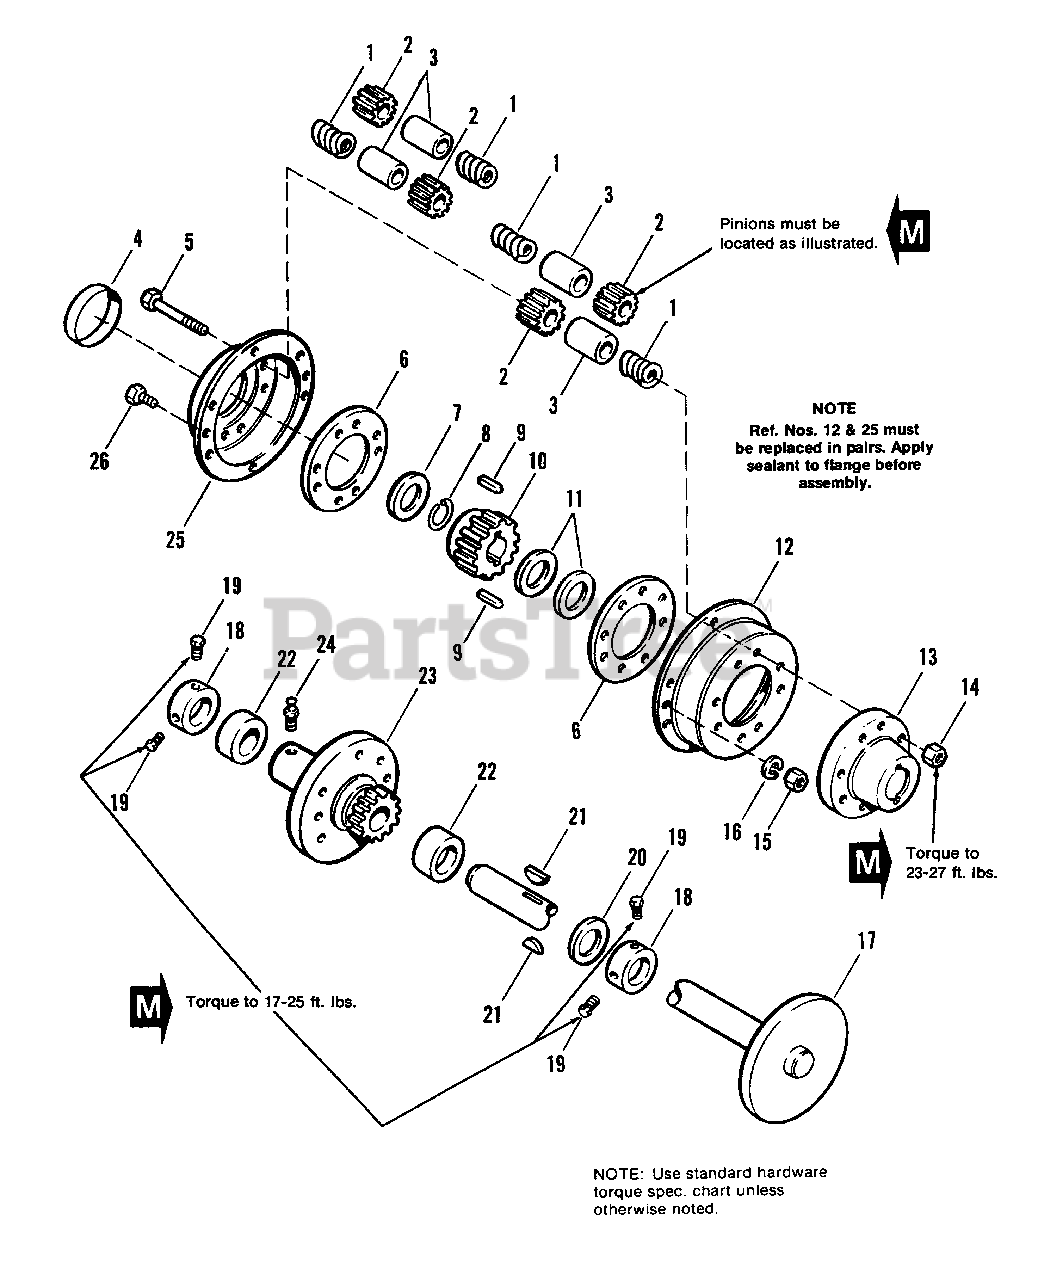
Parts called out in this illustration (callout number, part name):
2	* PINION, Differential
3	* SPINDLE, Differential
4	* SEAL, Cover
5	* CAPSCREW, Hex Hd., 3/8-16 x 2-1/2
6	* RING, Spacer
8	RING, Retaining
9	KEY, Hi-Pro
10	GEAR, Differential
12	* COVER, Differential
13	* CARRIER, Differential
14	* LOCKNUT, Hex, 3/8-16
15	* NUT, Hex, Full, 1/4-20
16	* LOCKWASHER, 1/4
17	AXLE ASSY., Rear
18	COLLAR, Set
19	SETSCREW, 5/16-18 x 1/2
23	HUB ASSY., Wheel, RH
24	FITTING, Grease
25	* COVER, Differential
26	* CAPSCREW, Hex Hd., 1/4-20 x 5/8
26	DIFFERENTIAL SUBASSY. (See Note Below)
